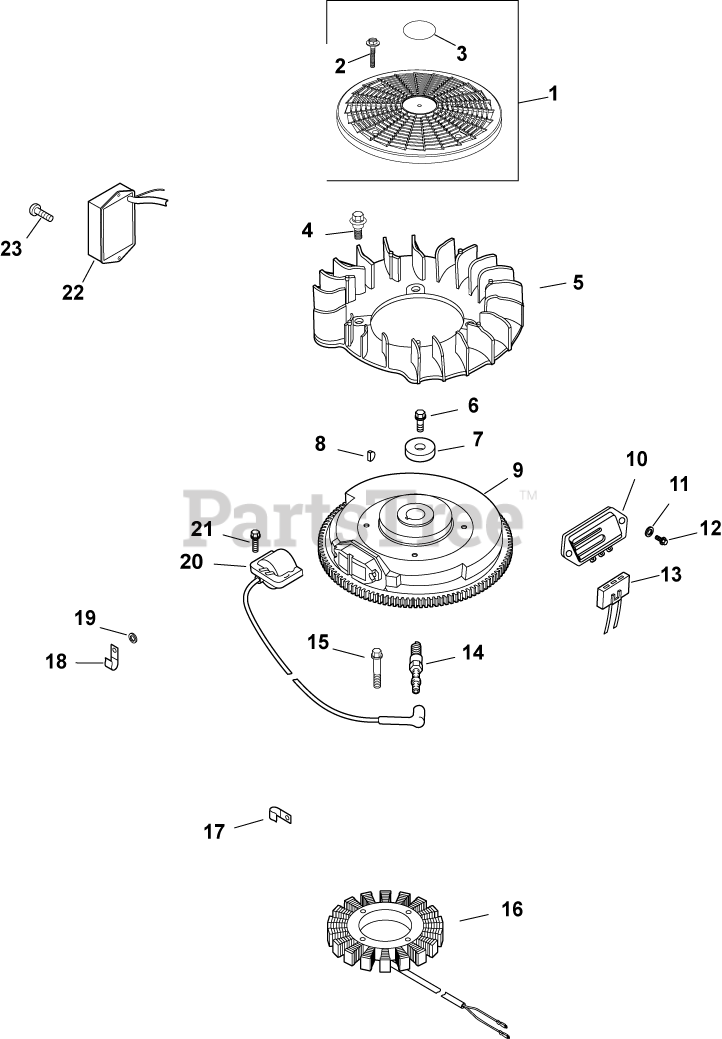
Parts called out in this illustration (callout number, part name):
1	KIT, GRASS SCREEN
2	SCREW, FLG SEMS M4X.7X25
3	DECAL, GRASS SCREEN USE 24 113 499-S
4	BOLT, SHOULDER
6	SCREW, FLG M10X1.5X45 - (#25086361S)
7	WASHER, FLAT 13/32"
8	KEY, 3/16" X 5/8"
9	FLYWHEEL ASSEMBLY-USE 24 025 58-S
10	REG/RECT-15 AMP (KM)-USE 41 403 10-S
11	WASHER, FLAT 3/16"
12	SCREW, PHL HD #11-16X7/8"
13	CONNECTOR, BODY (KM)-USE 25 155 41-S
14	PLUG, SPARK (STD)
15	SCREW, M5X0.8X25 - (#25086402S)
16	KIT, 15 / 20 AMP STATOR
17	CLIP, TUBE & WIRING (KM)
18	CLIP, CABLE
19	WASHER, FLAT 1/4" (O.D. 1/2")
20	MODULE, IGNITION
21	SCREW, FLG THD FRM M5X.8X20-(#25086399S)
22	MODULE, SPEED ADVANCE -USE 24 755 162-S
23	SCREW, THD FRM M4X0.7X10
2458452-S	MODULE, SPARK ADV -USE 24 584 89-S
